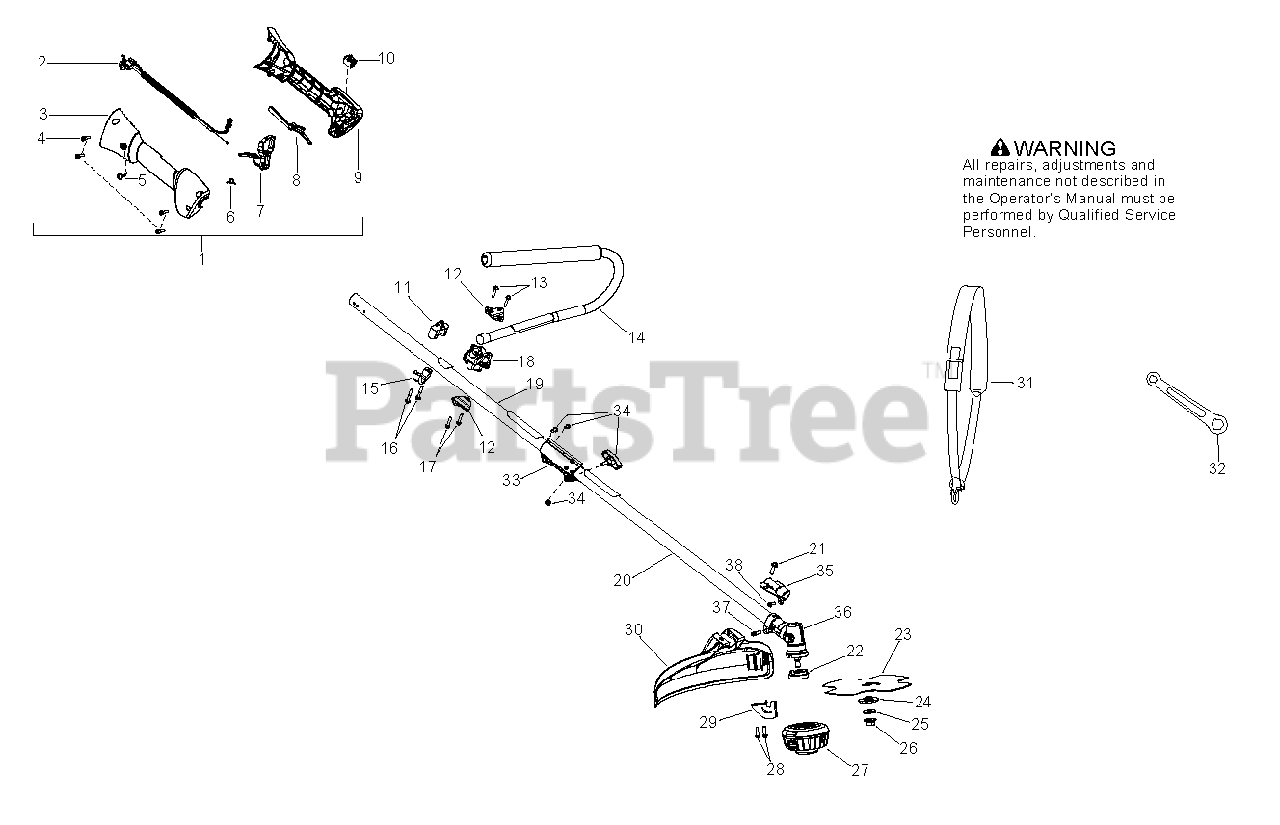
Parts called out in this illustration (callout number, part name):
2	ASSY CABLE/WIRE HARNESS
3	HANDLE HALF RIGHT
4	SCREW M4 X 1.75 PT 16MM
5	SCREW M4 X 1.75 PT 16MM
8	LOCKOUT TRIGGER
9	HANDLE HALF LEFT
10	STOP SWITCH
11	Upper Harness Clamp
12	CLAMP BRACKET
13	SCREW-10-14 X 13/16 (PL
15	Lower Harness Clamp
17	SCREW-10-14 X 13/16 (PL
18	CLAMP 1" HANDLEBAR
19	Drive Shaft Kit, Upper
21	SCREW 1/4-20 X 7/8 (TAP
22	DUST CUP , BLADE
23	ASSY BLADE
24	WASHER,BLADE RETAINING
25	WASHER BELLVILLE
26	NUT-FLANGE (LH)
27	Trimmer Head Assembly, Tng P25 Pp28 Counterclock
29	LINE CUTTER
30	KIT COMBO SHIELD
31	ASSY,SHOULDER STRAP
33	ASSY COUPLER BLACK
34	ASSY COUPLER BLACK
37	SCREW - CARB. ADAPTOR
38	SCREW 8-16 X 9/16 (PLAS
